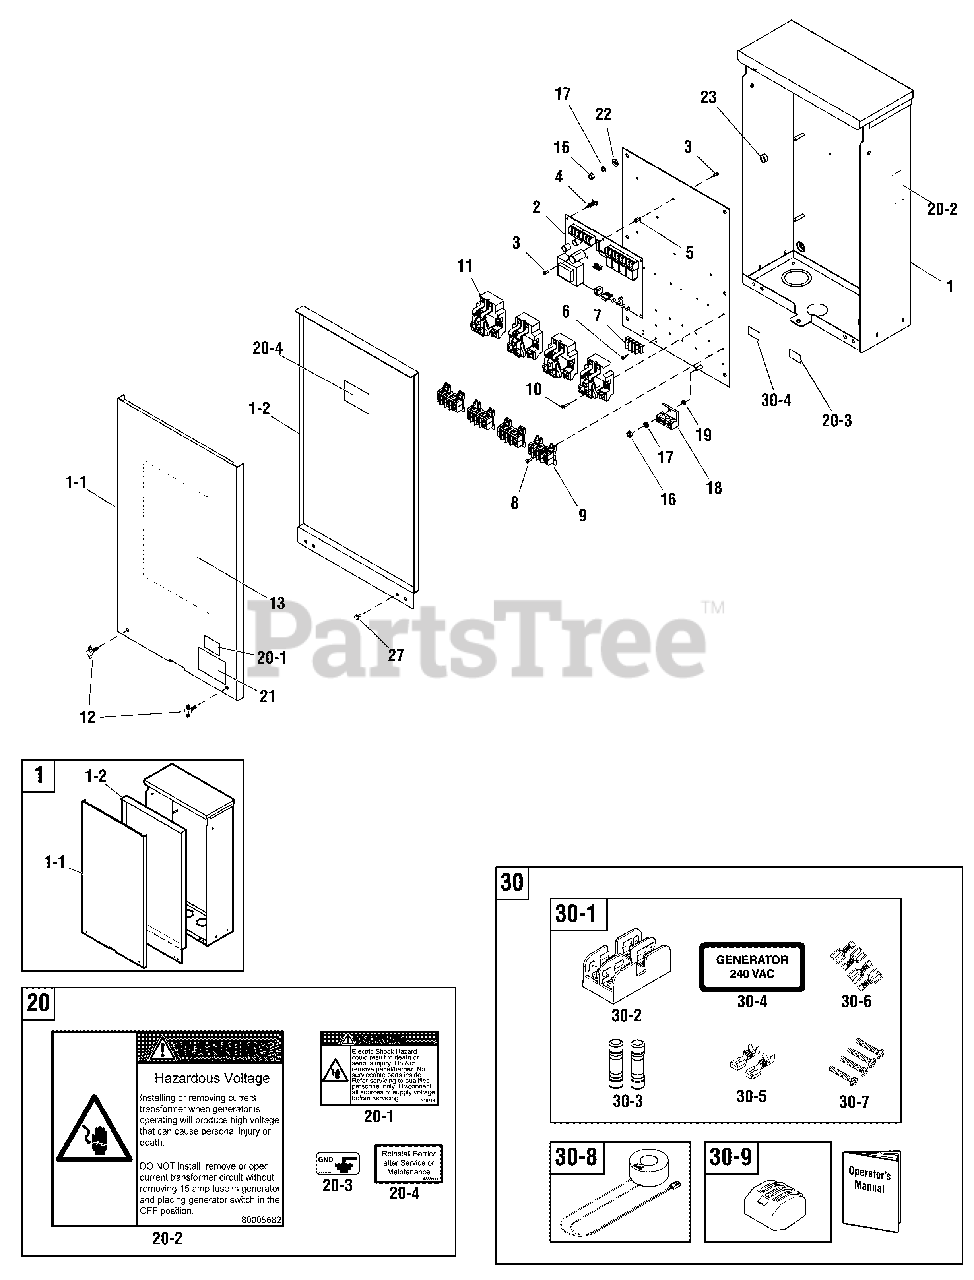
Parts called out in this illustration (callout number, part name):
1	ENCLOSURE
2	BOARD, Load Control Center Relay
3	* SCREW, Phillips Head, 6-32 x 3/8
4	SPACER, PCB Bard, 1/2"
6	* SCREW, Phillips Head, Trilobular, #6-32 x 3/8
8	* SCREW, Phillips Head, Trilobular, #8-32 x 5/8
9	TERMINAL BLOCK ASSEMBLY
10	PPHS, Trilobular, #8-32 x 3/8
16	*NUT, 1/4-20
17	*WASHER, Lock, 14
18	LUG
19	* WASHER, Shakeproof, Ext M6 - 1/4
20	DECAL SHEET-WARNINGS
20-1	DECAL, Warning, Shock
20-2	DECAL, Warning, Contact
20-3	DECAL, Ground
20-4	DECAL, Reinstall
22	* WASHER, Flat, 1/4
23	SPACER
27	TRILOBULAR, #10-32 x 3/8
30	KIT, Manual
30-1	KIT, Fuse
30-4	DECAL, Generator
30-5	LUG
30-6	LUG
30-7	SCREW
30-8	KIT, Current Transformer
30-9	BLOCK, Terminal w/Levers
